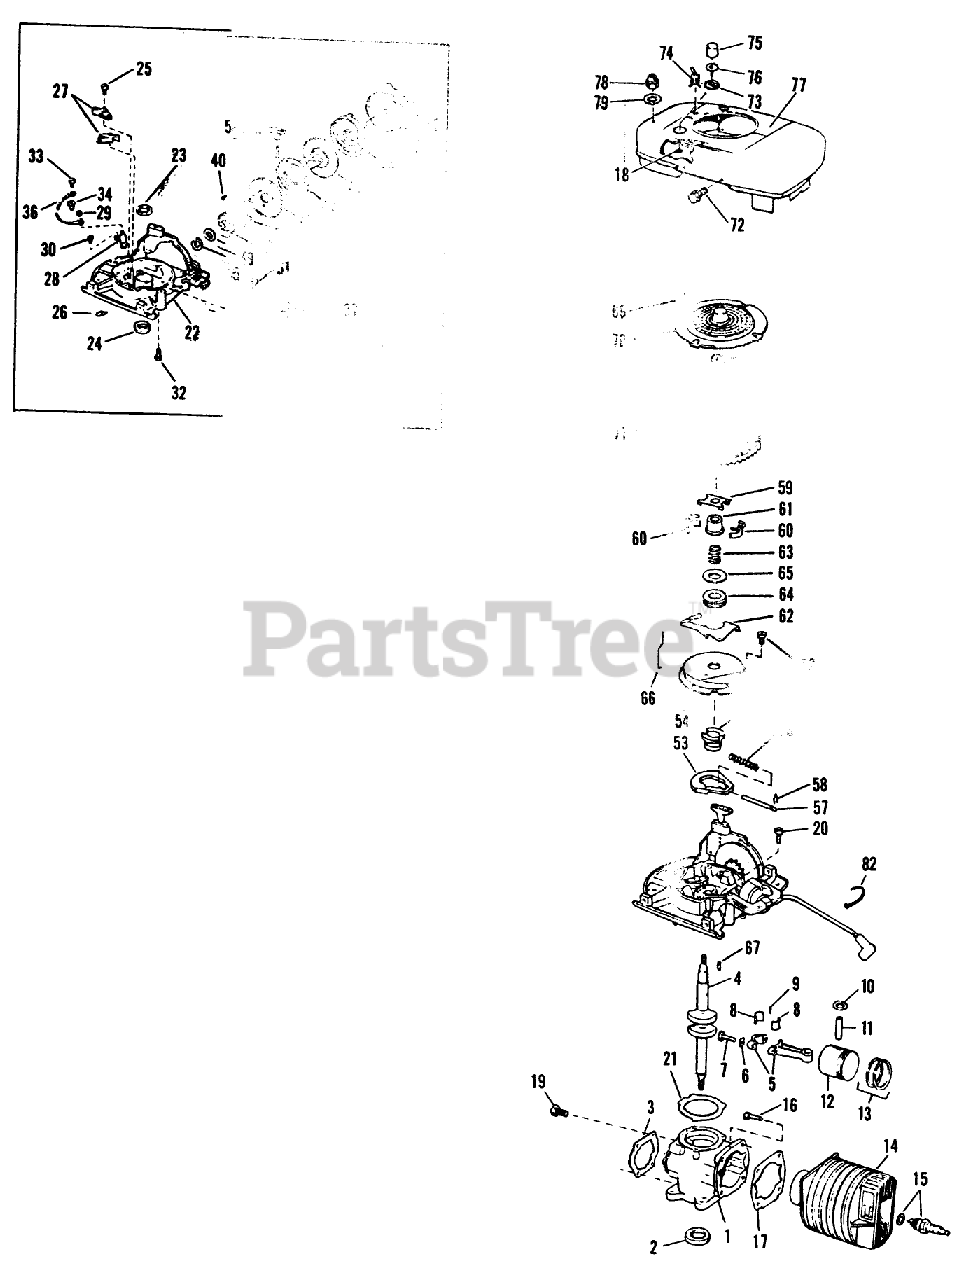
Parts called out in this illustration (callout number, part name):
3	GASKET S
8	LINER ASM
10	RING-RETAINING
15	Spark Plug Gasket RJ-12
17	GASKET S
18	LOCKNUT S
19	SCREW S
21	GASKET S
24	BEARING AY. S
27	BREAKER AY. S
32	SCREW S
34	NUT - CLIP
36	Terminal Lead Assy.
37	LEAD AY. S
40	SCREW S
41	PULLEY STARTER S
42	STARTER PINION S
44	SPRING S
46	STARTER SPRING S
49	WASHER S
51	SPRING S
52	SCREW S
53	FLYWEIGHT S
54	DUST COVER S
55	SPARK ADV. SPRING S
56	SPARK ADV. S
57	PIN,SPARK ADV. S
58	SPARK ADJ. SPRING
61	COLLAR S
62	LEVER-GOVERNOR S
64	THRUST COLLAR S
69	SCREW F
70	Screen Cup
71	FLYWHEEL S
72	SCREW S
73	CUP-BULB
73	Valve Screen
74	SWITCH AY.
74	Shroud Shield Assy.
75	PALNUT S
77	.Tank Ay
77	FUEL CAP AY S
78	PALNUT S
79	SWITCH AY.
83	CUP-BULB
